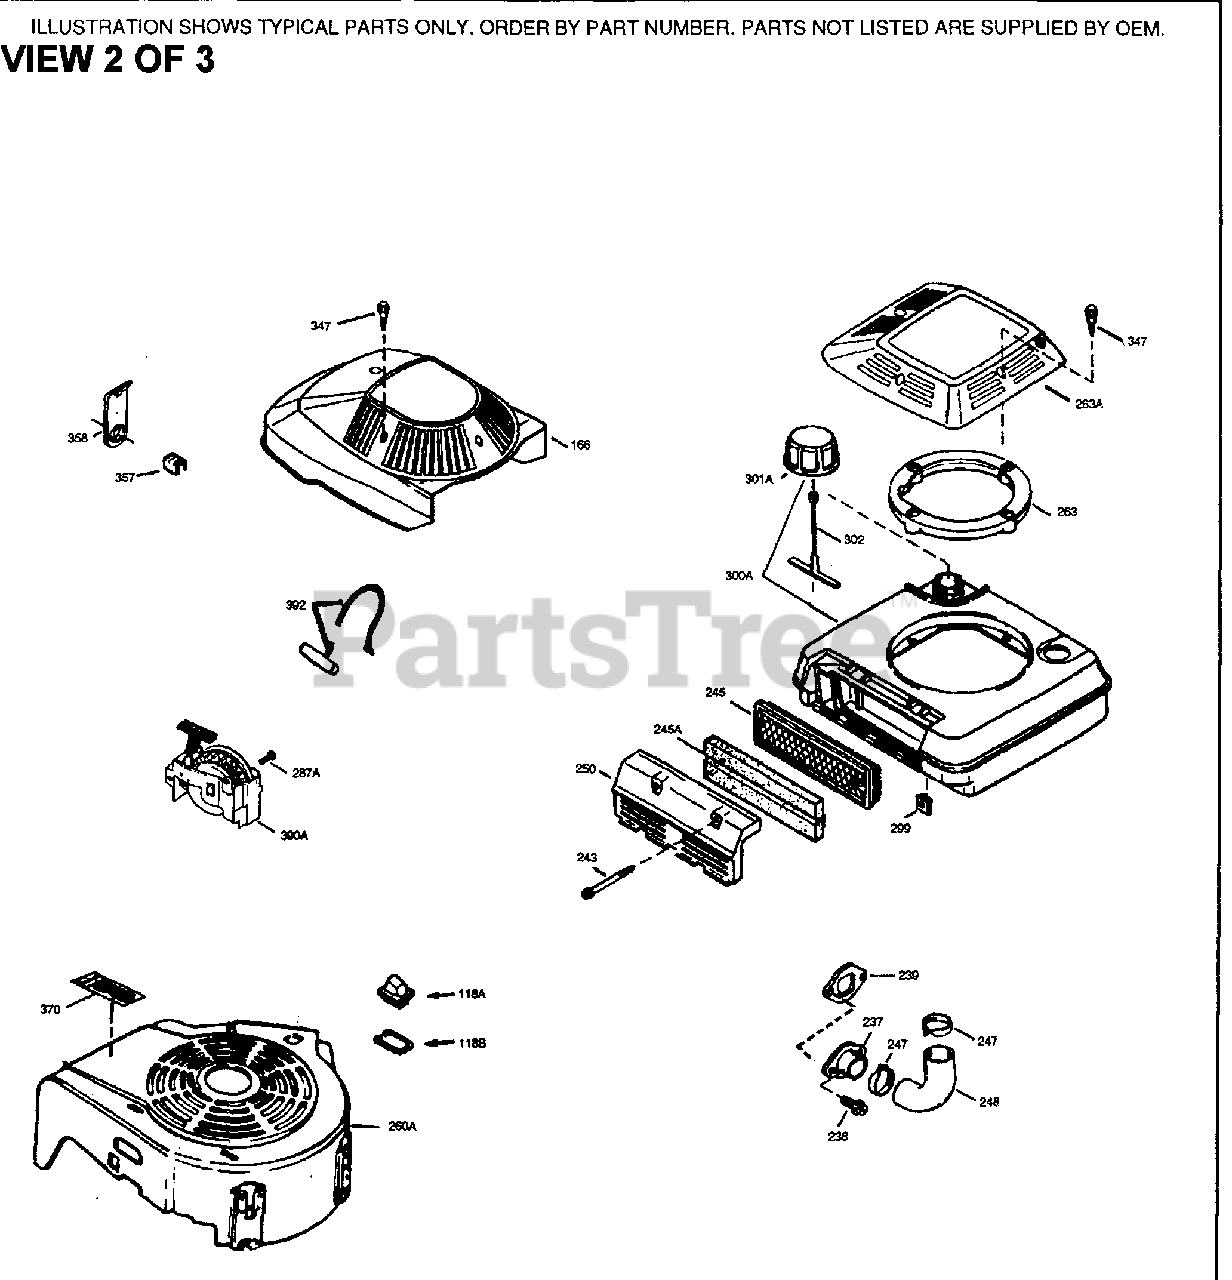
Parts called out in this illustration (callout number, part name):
238	Screw, 10-32 x 49/64"
239	* Air Cleaner Gasket
245	Air Filter (Paper) (also available in Packaged Part #740095 (Qty.2))
250	Air Filter Cover (Craftsman)
357	Starter Rope Retainer
370B	Control Decal
999	Summer Maintenance Kit (incl. Oil, Sp ark Plug, Air Cleaners (2), & Ultra-F resh)
